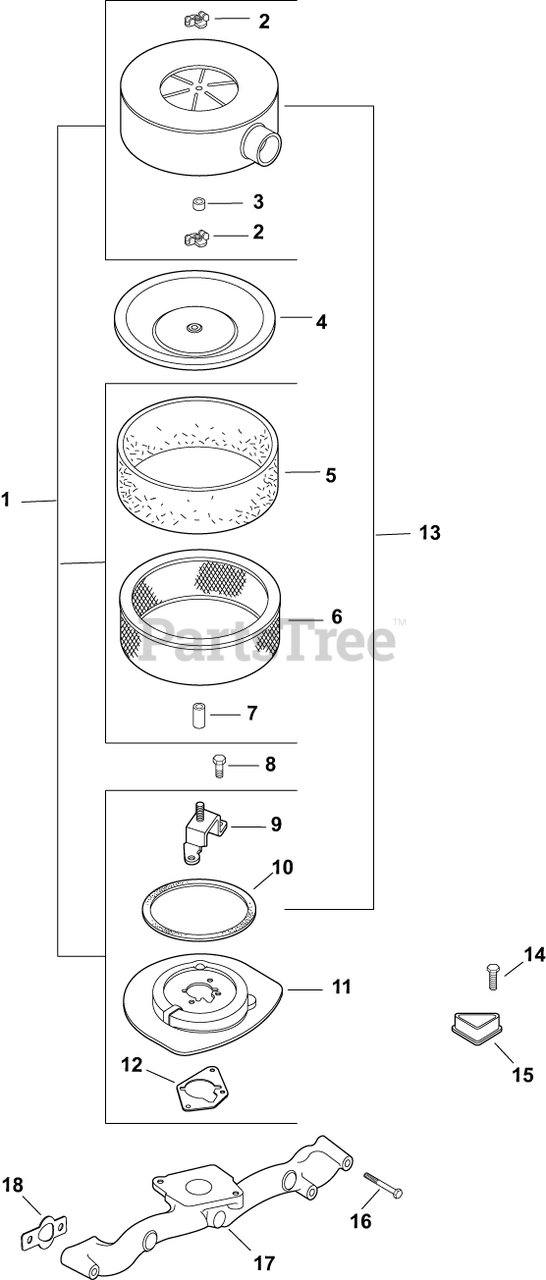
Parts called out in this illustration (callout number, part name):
1	KIT, DOME AIR CLEANER
2	NUT, WING
4	COVER, INNER AIR CLEANER
5	ELEMENT, PRECLEANER (LOW)
6	ELEMENT, AIR CLEANER - Also available Retail Packaged 47 883 03-S1 Air Filter Kit
7	SEAL, BREATHER
8	SCREW, FLG THD FRM M6X1.0X16
9	BRACKET, AIR CLEANER-USE 24 126 207-S
10	KIT, AIR CLEANER COVER SEAL
11	BASE, AIR CLEANER-USE 24 094 91-S
12	GASKET, AIR CLEANER BASE
13	COVER, AIR CLEANER
14	SCREW, WSH HD TAP #8-18X1/2"
15	COVER, BLOWER HOUSING USE 24 096 160-S
16	SCREW, FLG M6X1.0X55
17	MANIFOLD, METAL INTAKE
18	GASKET, INTAKE MANIFOLD USE 24 041 79-S
